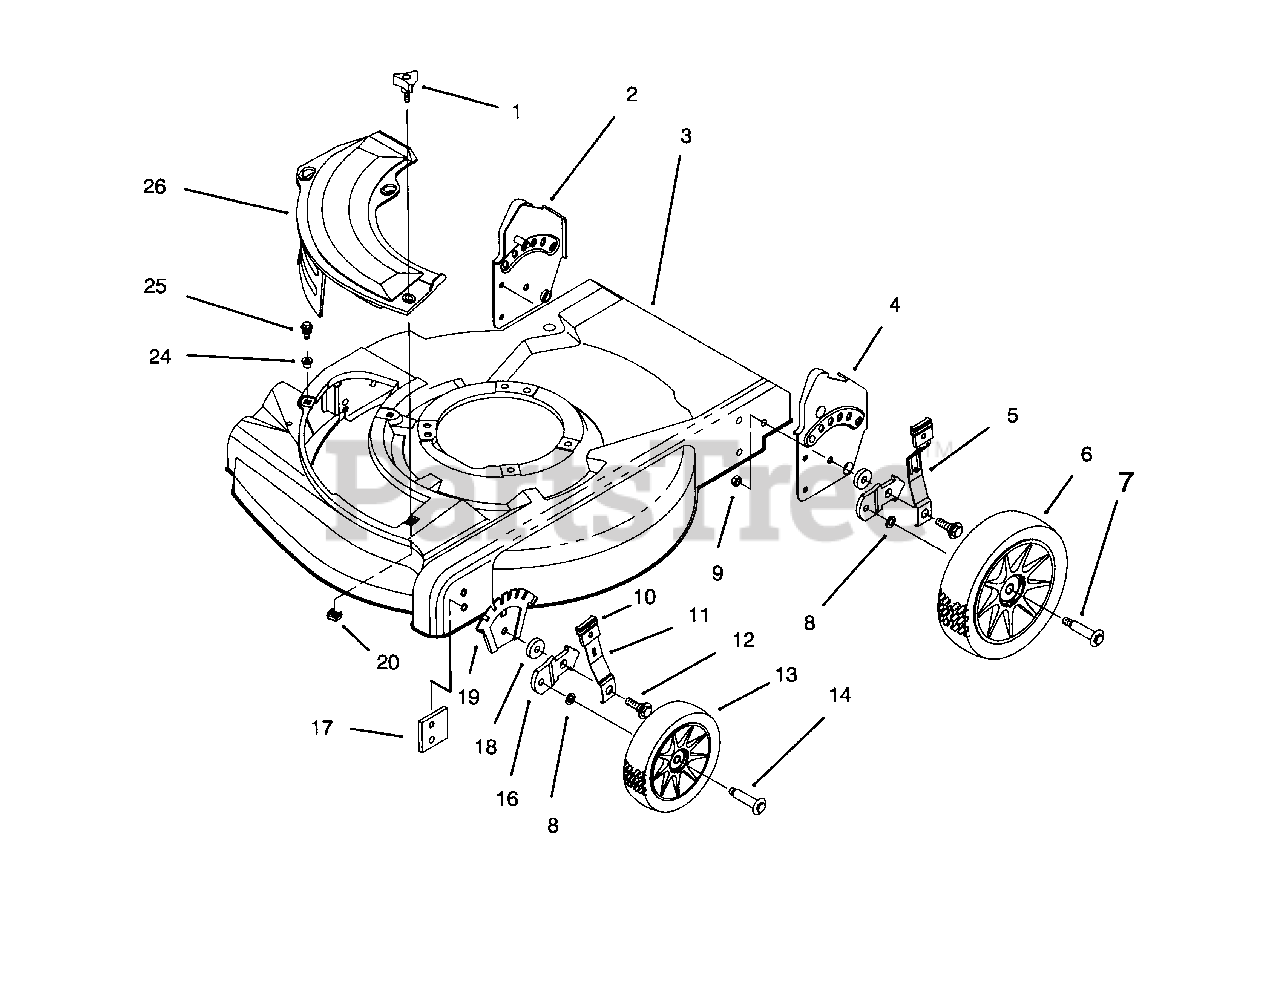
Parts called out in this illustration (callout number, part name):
1	Knob
2	Handle Bracket Ass'y-RH
3	Housing & Baffle Ass'y (Incl. Ref. #20, 21, 23, &24)(Incl. Ref. #3, 4, & 11 pg.3)
4	Handle Bracket Ass'y-LH
5	Spring Arm Assembly
6	Wheel Ass'y-8"
7	Bolt-Wheel
8	Washer-Wheel Bolt
9	Nut-Lock
10	Knob-H. O. C. Lever
11	Arm-Spring, Front
12	Bolt-Shoulder
13	Wheel Ass'y-6"
14	Bolt-Wheel
16	Bracket-H. O. C.
17	Plate-Baffle
19	Plate-H. O. C. Front
20	Nut-Cage
24	Grommet-Plastic
25	Screw-Thread Forming
26	Plate-Cover, Mulch
